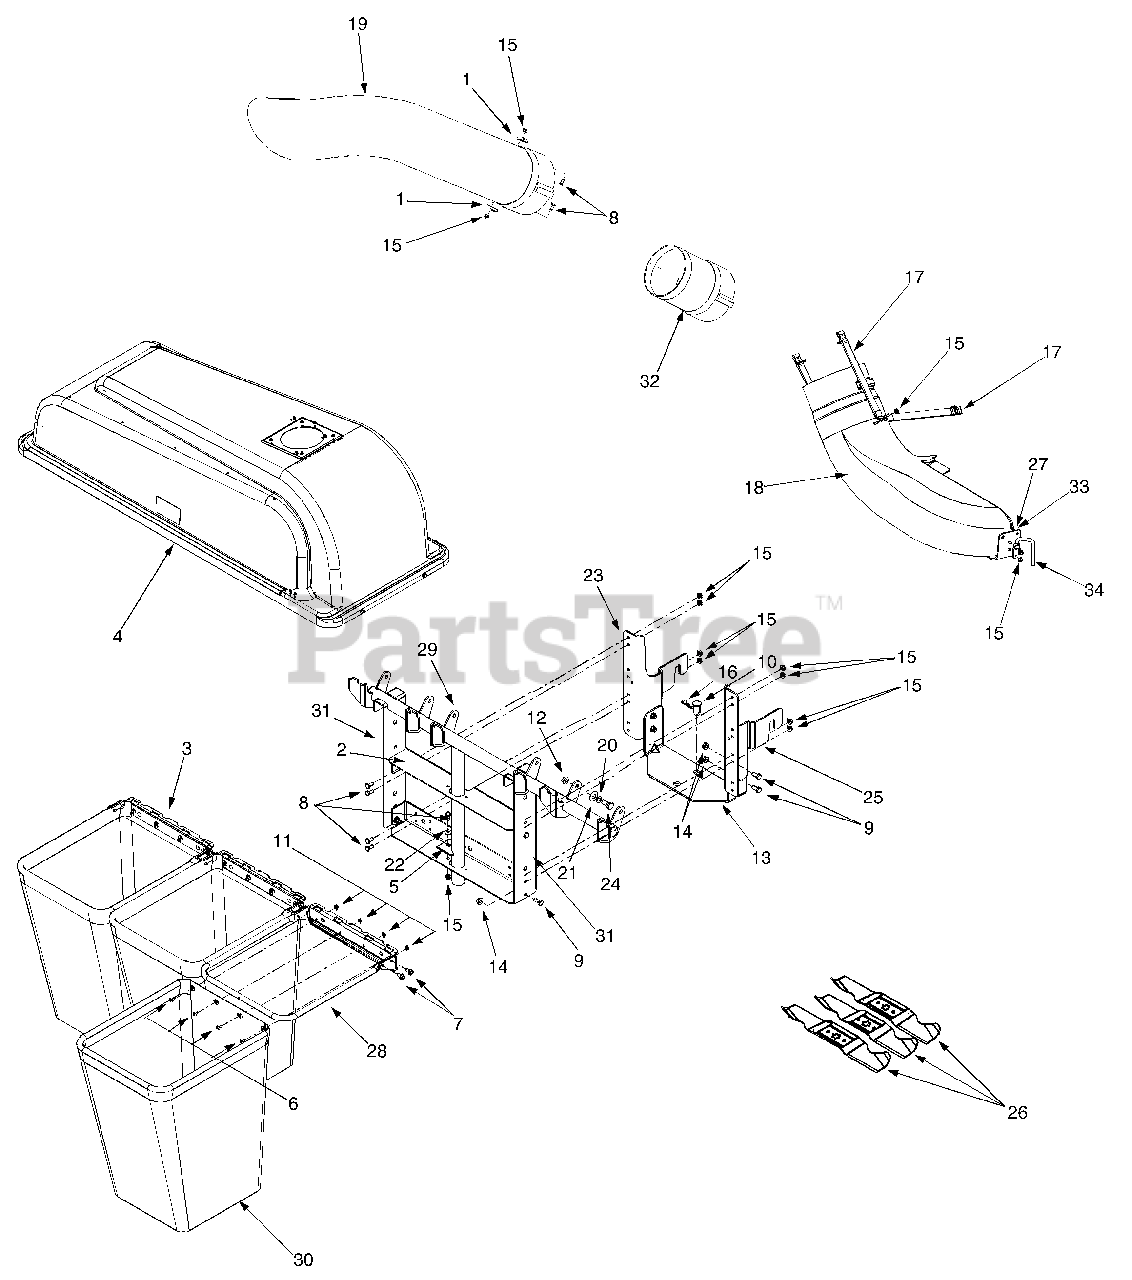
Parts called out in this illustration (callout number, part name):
1	Retainer Hook Bracket
2	Catcher Support Bracket
4	Cover Assembly Complete
6	Screw, #10-24 x .5
7	Self Tapping Screw, 5/16-18 x .625
8	Hex Cap Screw, 1/4-20 x .62
9	Hex Cap Screw, 5/16-18 x .75
10	Clevis Pin
11	Hex Sems Nut, 10-24
12	Hex Flange Lock Nut, 3/8-16
14	Hex Flange Lock Nut, 5/16-18
15	Hex Flange Lock Nut, 1/4-20
16	Internal Cotter Pin, .148 x 3
17	Retainer Strap Assembly
18	Discharge Chute
19	Chute Tube
20	Flat Washer, .51 x .75 x .033
21	Belleville Washer
22	Bell Washer, .265 x .75 x .062
24	Shoulder Screw, .50 x .27, 3/8-16
26	High Lift Blades 18.50"
27	Hex Washer Screw 1/4-20 x 1.0
30	Grassbag
32	Extension Tube
33	Flat Washer .28 ID x .74 OD
34	Mounting Rod
